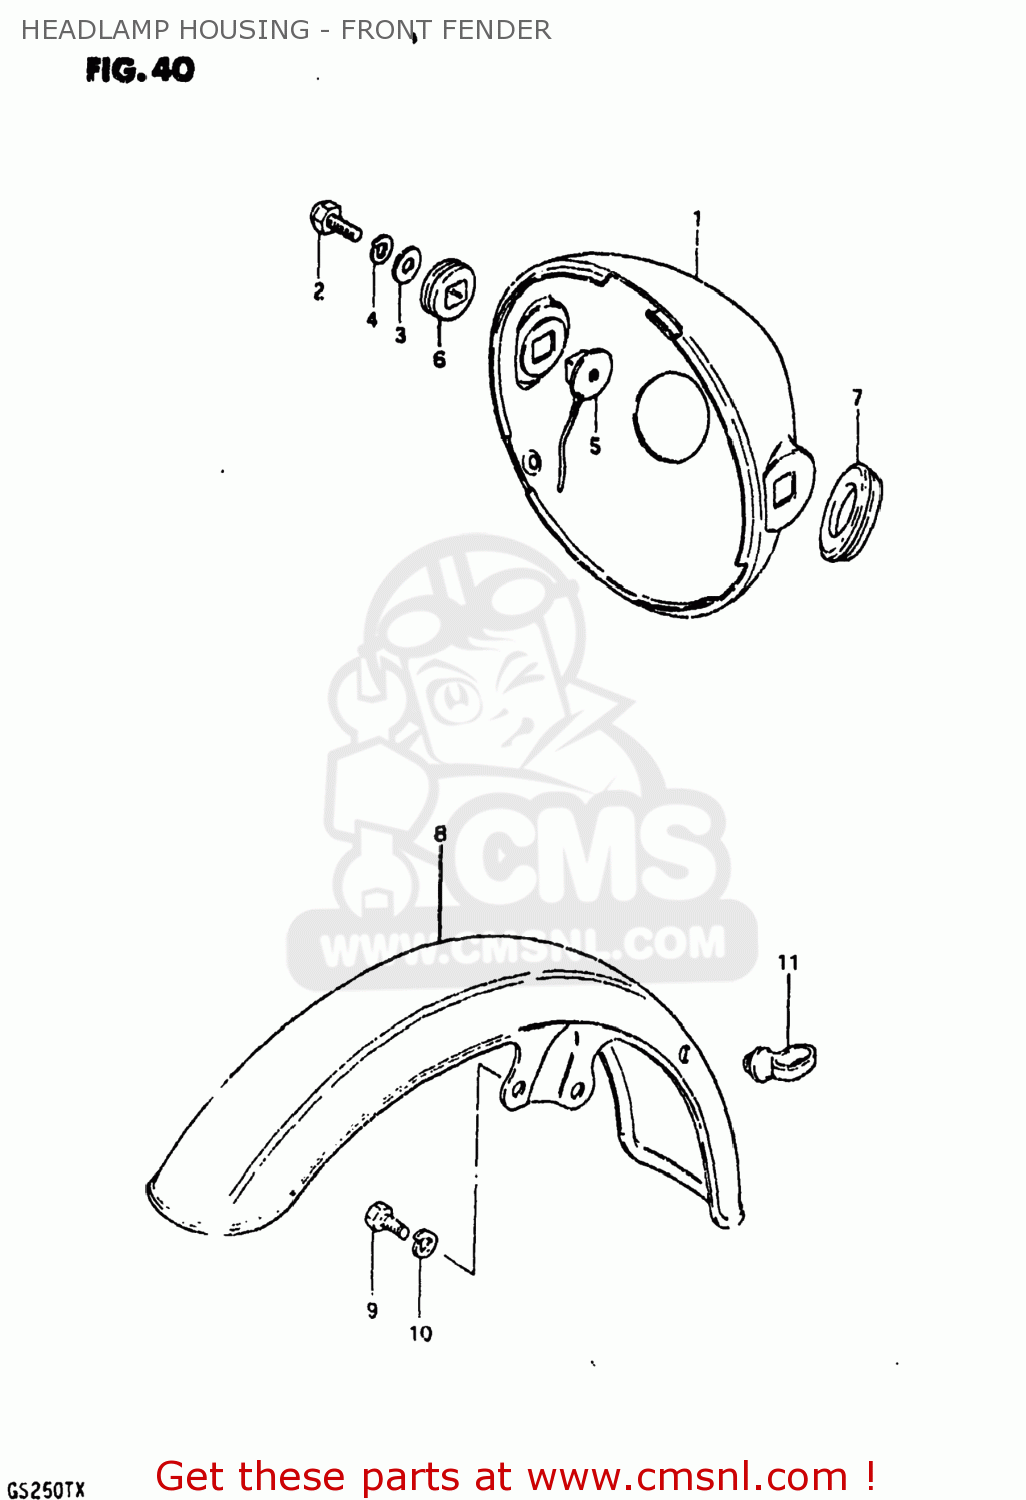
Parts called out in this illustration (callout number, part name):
1	HOUSING COMP,HEADLAMP
2	BOLT
3	WASHER
4	LOCK WASHER
5	SPACER,HEADLAMP HOUSING
6	CUSHION,HEADLAMP HOUSING
7	GROMMET,HEADLAMP HOUSING
8	FENDER,FR
9	BOLT
10	LOCK WASHER
11	GUIDE,CABLE
